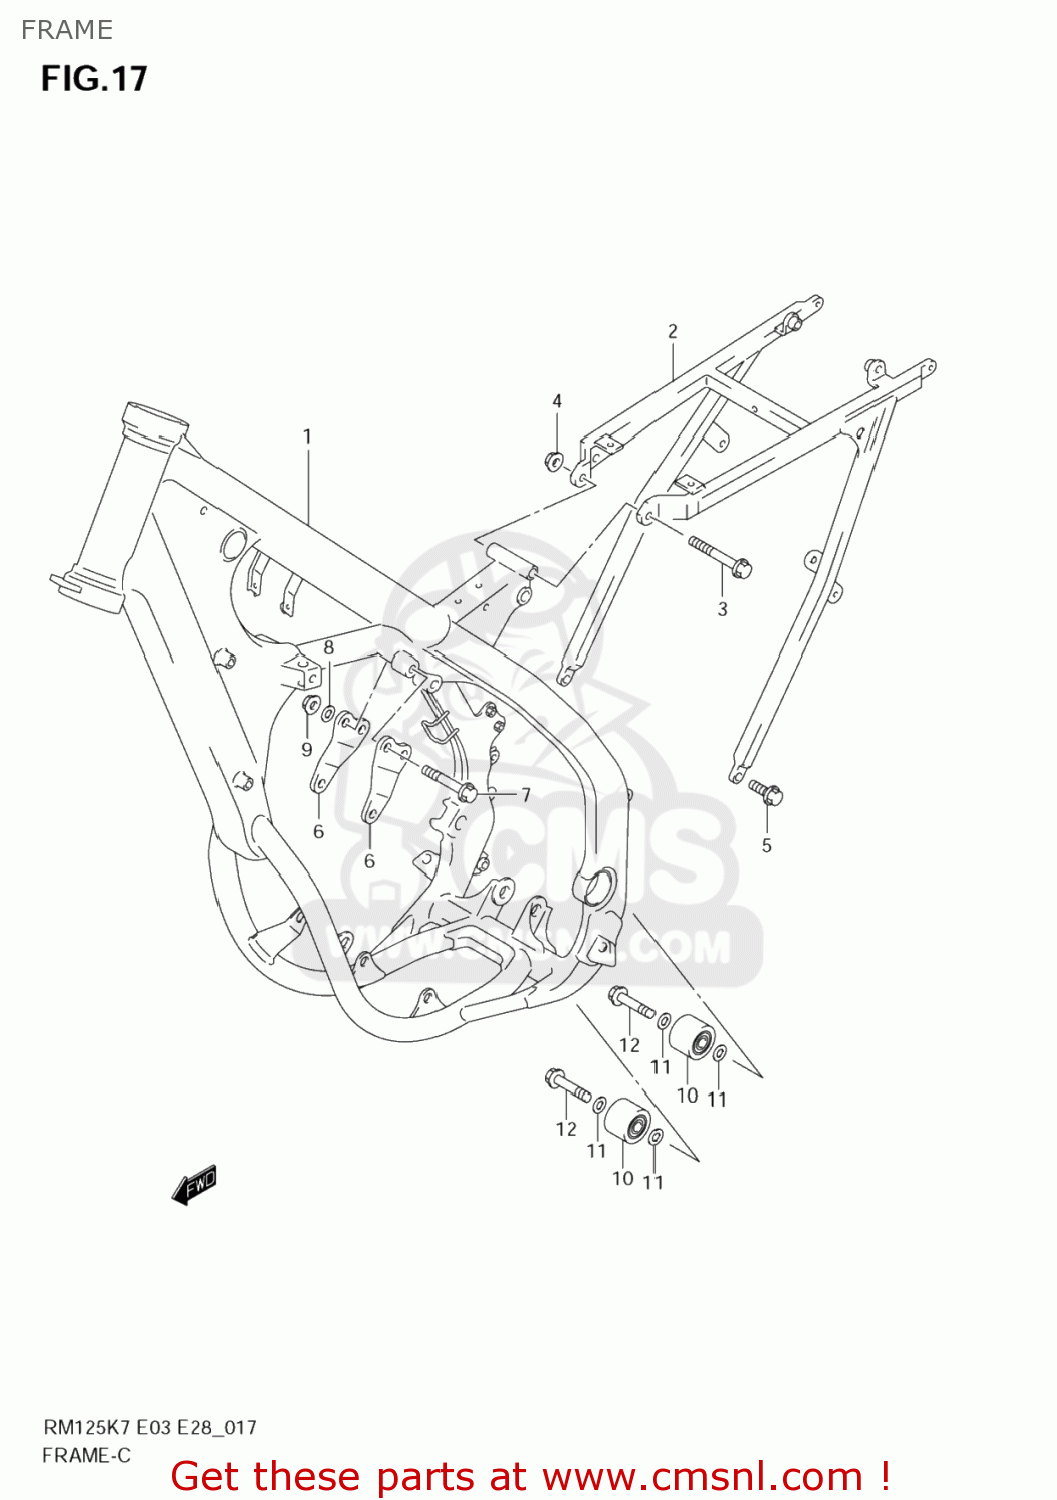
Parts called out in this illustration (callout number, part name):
1	FRAME(GRAY)
2	RAIL,SEAT
3	BOLT(8X100)
4	NUT
5	BOLT(8X16)
6	PLATE,ENG MTG UPR
7	BOLT(8X45)
8	WASHER
9	NUT
10	ROLLER,CHAIN
11	SHIM(8X12X1)
12	BOLT(8X41)
